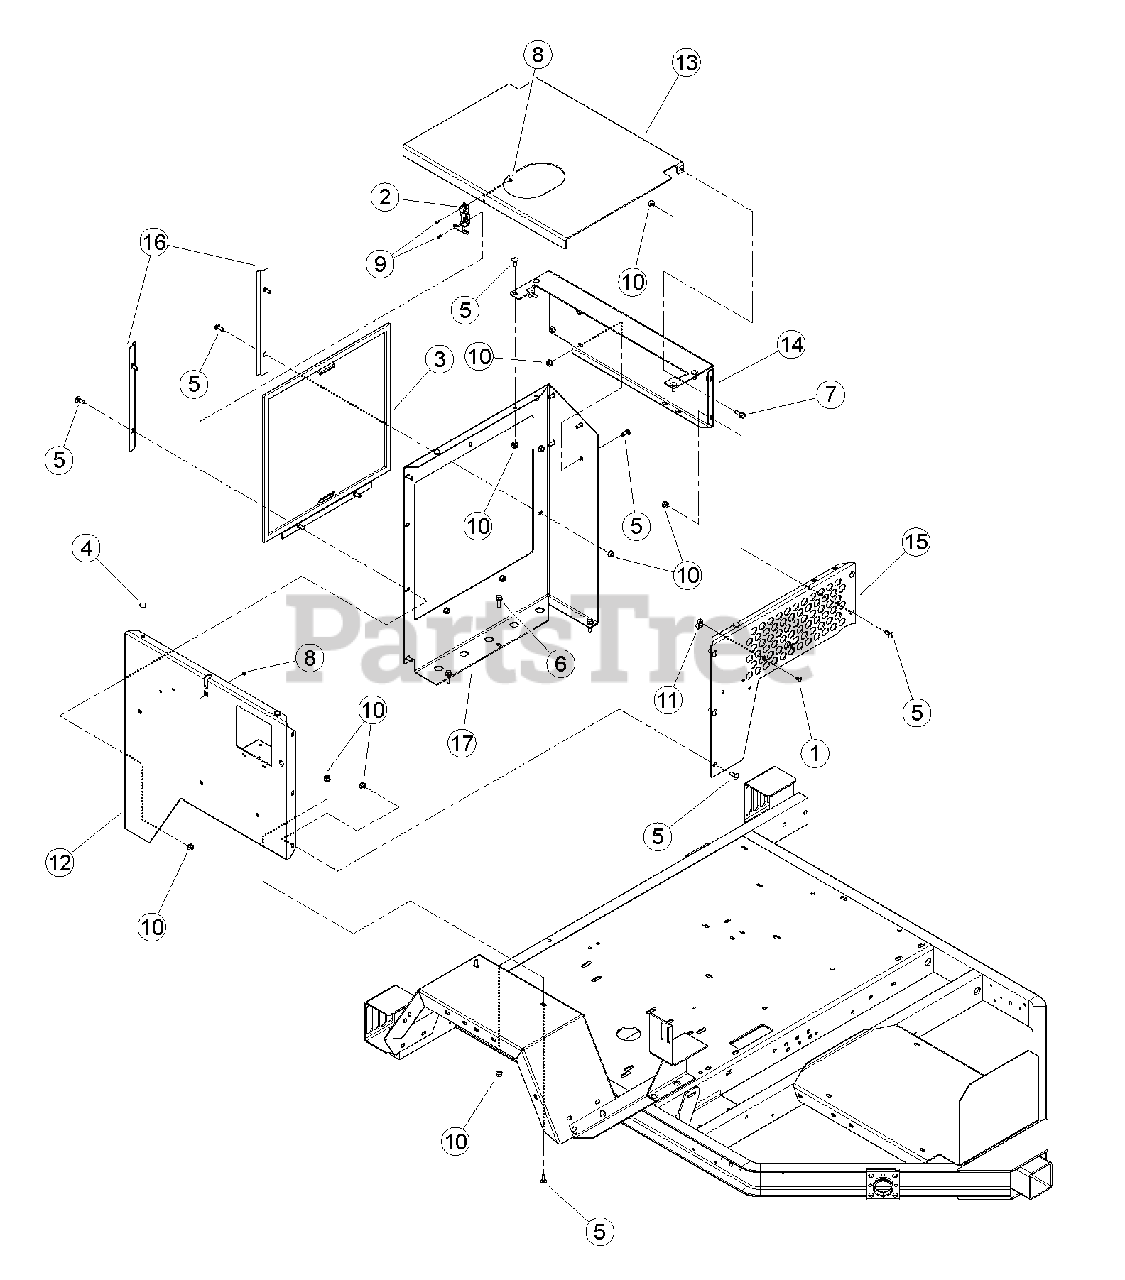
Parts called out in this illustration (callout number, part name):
1	RIVET, 1/4 X 3/4 ST POP
2	LATCH, FLEXIBLE DRAW
3	SCREEN, RADIATOR INLET
4	BUMPER, RUBBER
5	BOLT, 3/8 X 1" GR5 CRG NC ZP
6	BOLT, 3/8 X 1-1/4 FLANGE NC
7	BOLT, 3/8 X 1 FLANGE NC
8	NUT, 10/24 NYLOCK TYPE NM ZP
9	SCREW, MCH 10-24 X 1/2" PAN HD PH ZP
10	NUT, 3/8-16 NYLOCK FLANGE
11	CLAMP, CABLE MOUNT
12	WELDMENT, SIDE COVER PANEL
13	HOOD, ENGINE
14	SIDE, ENGINE COVER
15	COVER, REAR ENGINE
16	BRACKET, SCREEN HOLDER
17	PANEL, RADIATOR COVER
